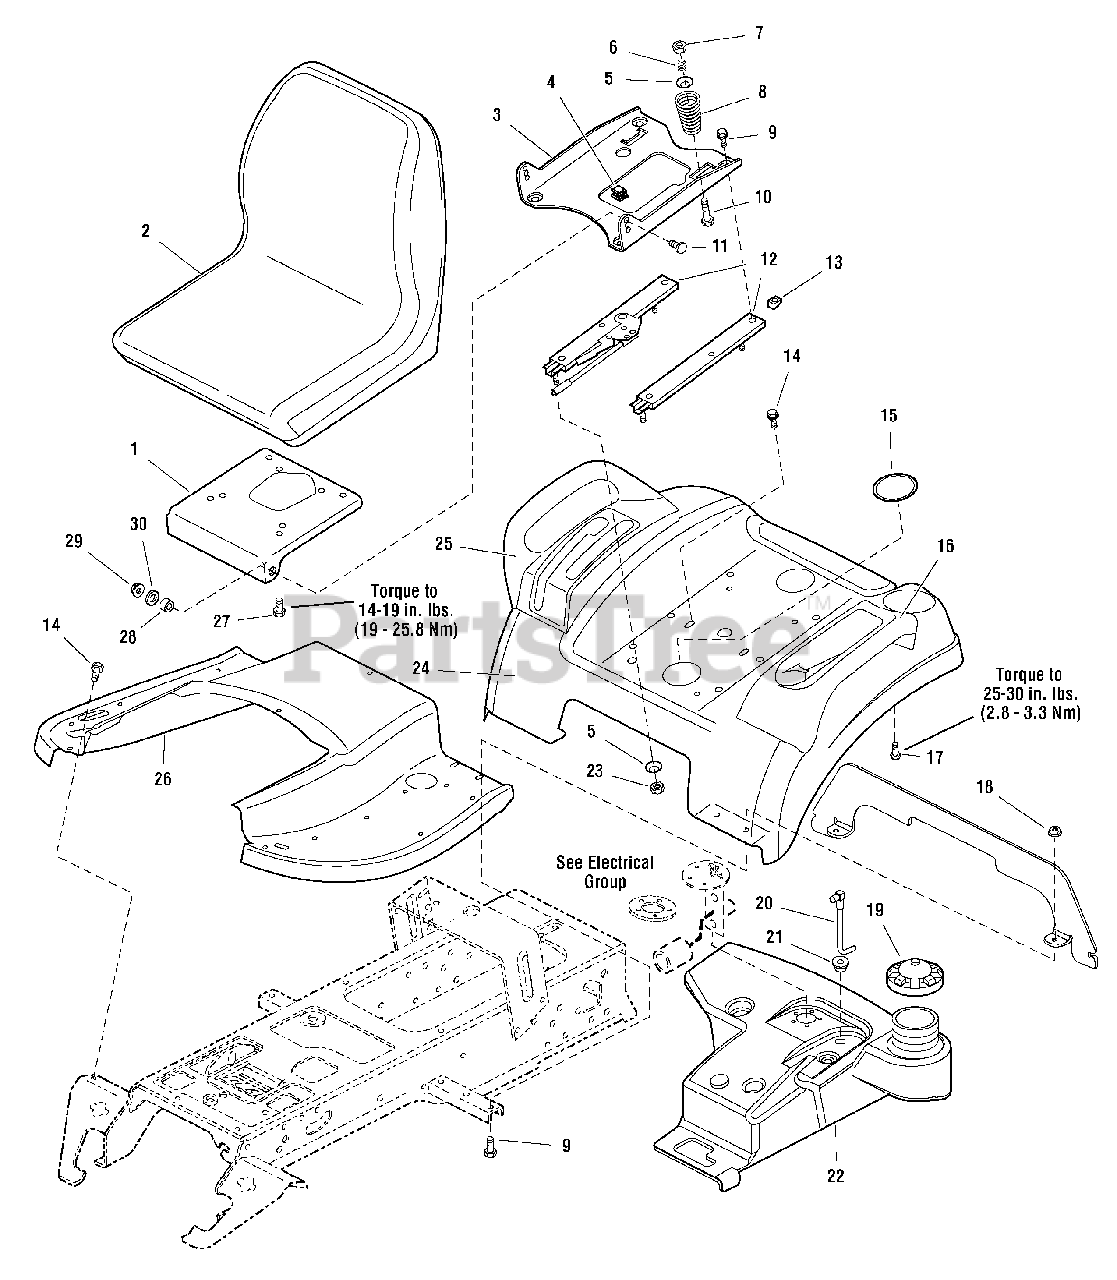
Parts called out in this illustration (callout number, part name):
1	BRACKET, 1-5/8 x 1-3/4
2	SEAT, 18" Back
3	SUPPORT, Seat
4	CLIP, Wire
5	WASHER, Spring, 5/16 x 1-1/4
6	SPRING, Compression
7	NUT, Hex Lock ESNA Light, 5/16-18
8	SPRING, Compression
9	CAPSCREW, Hex Flange Whiz Lock, 5/16-18 x 3/4
10	CARRIAGE BOLT, 5/16-18 x 2
11	CARRIAGE BOLT, 3/8-16 x 1
12	SLIDE, Seat
13	NUT, Speed, Lug Type, 5/16-18
14	CAPSCREW, Hex Washer Head Taptite, 5/16-18 x 5/8
15	PLUG, Plastic
16	POD, with Cup Holder, LH
17	CAPSCREW, Hex Washer Head, 1/4-20 x 5/8
18	NUT, Hex Flange Whiz Lock, 5/16-18
19	CAP, Gas
20	TUBE & ELBOW ASSEMBLY
21	BUSHING, 3/8 x 9/16 x 5/8, Rubber
22	TANK, Fuel
23	NUT, Hex KEPS, 5/16-18
24	DECK, Seat, Red
25	POD, RH with 2 Slots
26	TUNNEL, Red
27	CAPSCREW, Hex Flange Whiz Lock Dog Point, 5/16-18 x 1
28	SPACER, 25/64 x 5/8 x 3/16, Hardened
29	NUT, Hex Flange Two-Way Lock, 3/8-16
30	WASHER, 3/8
